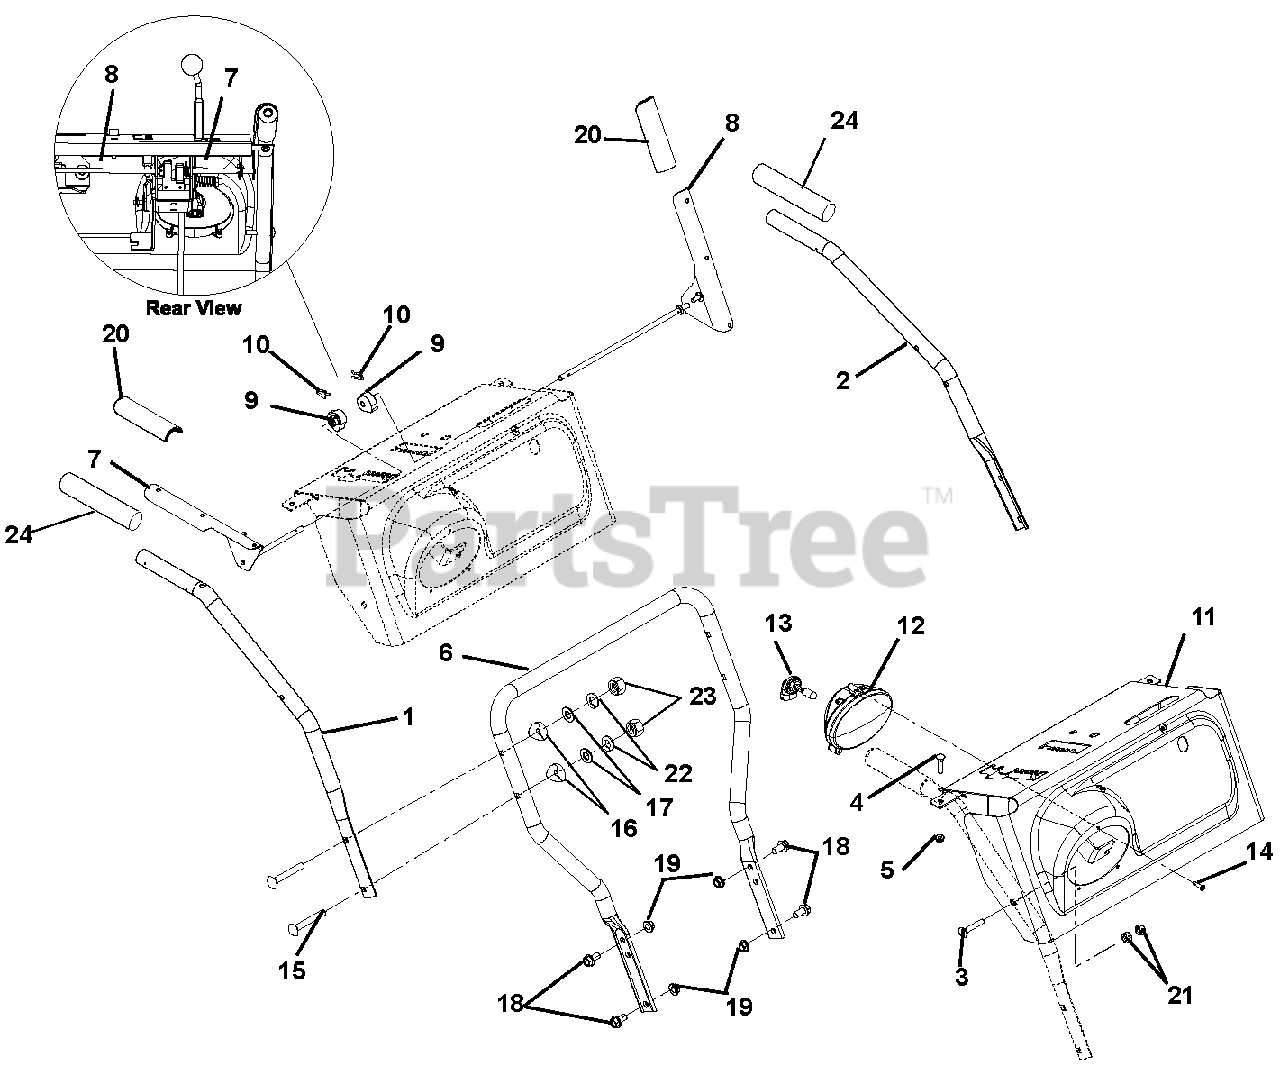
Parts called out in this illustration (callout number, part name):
1	Handlebar, Upper Right Hand
2	Handlebar, Upper Left Hand
3	Bolt, Round Head Square Neck .31-18 x 1.75 Grade 5
4	Bolt, Round Head Square Neck .25-20 x 1.25
5	Nut, Locking Top Flange .25-20
6	Handlebar, Lower
7	Lever, Right Hand-Attachment
8	Lever, Left Hand-Traction
9	Cam, Interlock
10	Pin, Spring Clip
11	Panel with Control Decal
12	Light, Halogen Assy. (Bulb Included)
13	Bulb, Light Halogen
14	Screw, Tapping 10-16 x .75 Hi-Lo
15	Bolt, Round Head Square Neck .31-18 x 2.25
16	Spacer, Handlebar
17	Washer, Flat-Steel .38 x .875 x .083
18	Bolt, Screw Hex Flanged Whiz Lock Head .38-16 x .75
19	Nut, Locking-Top-Flange .38-16
20	Grip, Clutch Lever
21	Nut, Locking-Center .31-18
22	Washer, Locking .31 x .078 Regular
23	Nut, Locking-Nylon .312-18
24	Handle Grip
